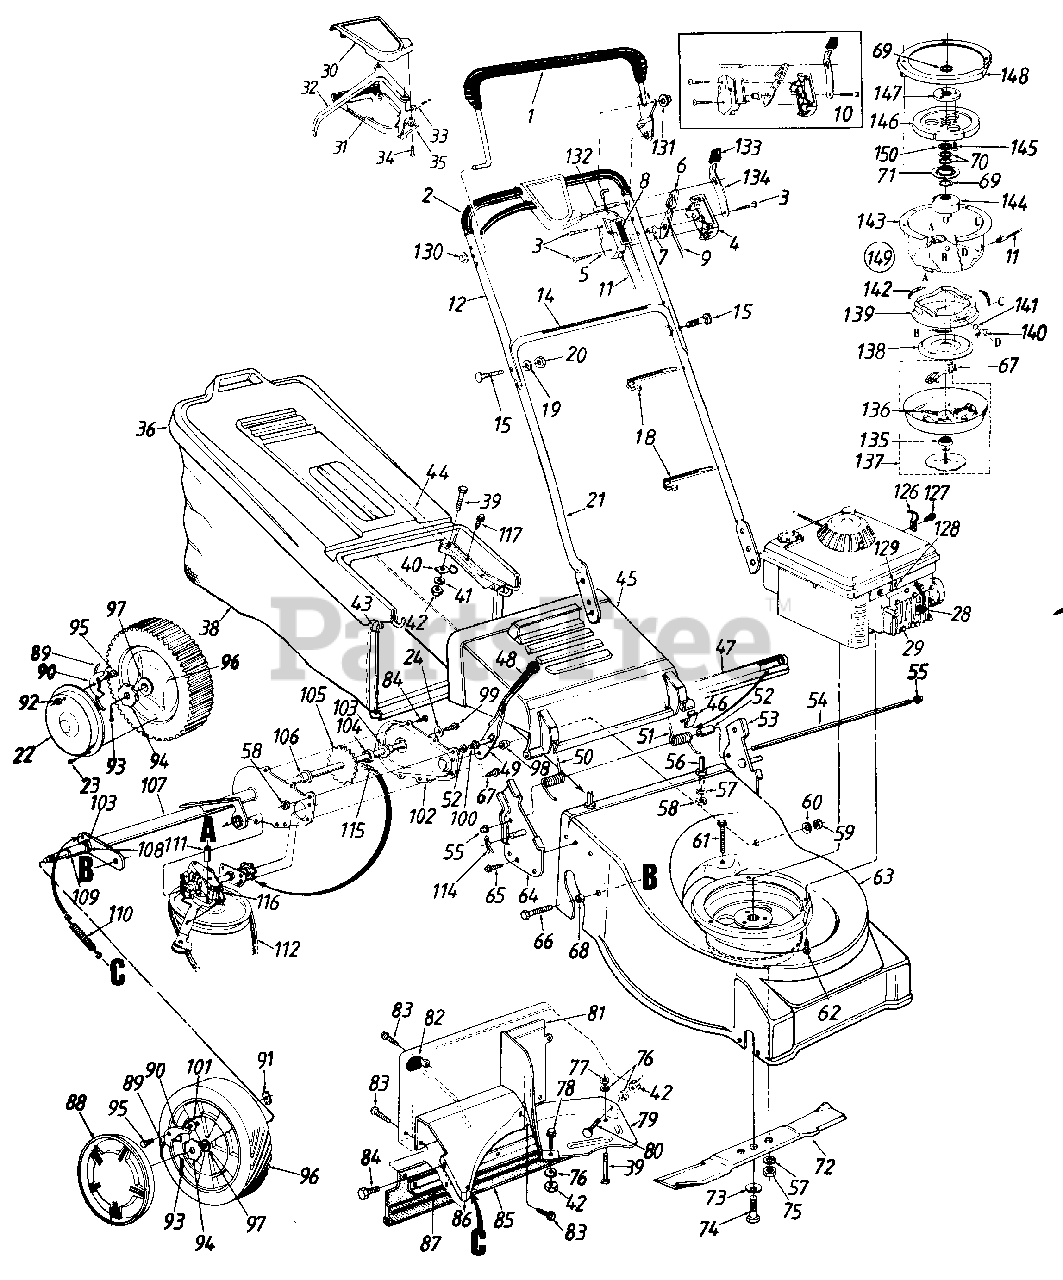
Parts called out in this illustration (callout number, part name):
1	Control Handle Ass'y.
2	Grip
3	Truss Mach. B-Tap Scr. #12 x 1.5" Lg.
4	Control Panel Half
5	Clutch Panel Half
6	Throttle Control Lever
7	Control Disc Pin
8	Control Label-Throttle
9	Throttle Wire-58" Lg.
10	Control Housing Comp.
11	Control Cable-52" Lg.
12	Upper Handle
14	Instruction Label-Handle
15	Curved Carriage Bolt 5/16-18 x 1.38" Lg.
18	Cable Tie
19	L-Wash. 5/16" I.D.'
20	Hex Nut 5/16-18 Thd.
21	Lower Handle
23	Pan Hd. Tap Scr. #12 x .50" Lg.
24	Bell-Wash. .265" I.D. x .75"
28	Spark Plug Boot
29	Engine
30	Control Cover Half-Upper
31	Control Cover Half-Lower
32	Control Lever
33	Drive Cable-53" Lg.
34	Flat C-Sunk Hd. Tap Scr. #10 x .75" Lg.
35	Cable Mtg. Cap
36	Hardtop Bag Cover
38	Grass Bag
39	Truss Mach. Scr. 1/4-20 x 1.0" Lg.
40	Mounting Clamp
41	Fl-Wash. .281" I.D. x .62"
42	Hex Nut 1/4-20 Thd.
43	Front Catcher Frame
44	Rear Catcher Frame
45	Chute Deflector
46	Deflector Plug
47	Seal-Extrusion
49	Spring Lever
50	Torsion Spring-R.H.
51	Torsion Spring-L.H.
52	Spacer.255" I.D.
53	Handle Brkt. Ass'y.-L.H.
54	Hinge Pin 17.75" Lg.
55	Cap Speed Nut
56	Shld. Pin 3/8-24 x 1.43" Lg.
57	L-Wash. 3/8" I.D.
58	Hex Jam Nut 3/8-24 Thd.
59	Hex L-Nut 3/8-24 Thd.
60	Bell-Wash. .38" I.D. x .88"
61	Hex Wash. Hd. Tap Scr. 1/4-20 x 1.5" Lg.
62	Hex L-Wash. Hd. Scr. 3/8-16 x 1.5" Lg.
63	21" Deck Ass'y.
64	Handle Brkt. Ass'y.-R.H.
65	Hex L-Wash. Hd. AB-Tap Scr. 1/4 x .62" Lg.
66	Hex Wash. Hd. Tap Scr. 3/8-16 x .75" Lg.
67	Hex Wash. Hd. Tap Scr. 1/4-20 x .5" Lg
68	Spacer.385" I.D.
69	Serrated Washer 1.0" I.D.
70	Wave Washer 1.005" I.D.
71	Serrated Pulley Half
72	21" Blade
73	Bell-Wash. .46" I.D. x .88"
74	Hex Bolt 7/16-20 x 2.0" Lg. (Gr. 5)
75	Hex Nut 3/8-24 Thd. (Gr. 8)
76	L-Wash. 1/4" I.D.
77	Hex Jam Nut 1/4-20 Thd.
78	Hex Bolt 1/4-20 x .85" Lg.
79	Rear Belt Baffle
80	Carr. Bolt lh-20 x .50" Lg.
83	Torx Mach. AB-Tap Scr. 1/4 x .62" Lg.
84	Hex B-Tap Scr. 1/4 x .38" Lg.
85	Rear Flap
89	Plastic Spring
90	Pawl.345" I.D.
91	Weld Nut 1/4-20 Thd.
92	Hex Ins. L-Nut 1/4-20 Thd.
93	Cotter Pin 1/8" Dia.
94	Ratchet Wheel 1.62" O.D.
95	Shld. Bolt .342" Dia. x .268"
96	** Wheel Ass'y. Comp.-Rear
97	** Flange Ball bearing 1/2" I.D.
98	Shld. Spacer .50" Dia.
99	Hex Bolt 1/4-20 x .62" Lg. (Gr. 5)
100	Shld. Pin 3/8-24 x 1.43" Lg.
101	Bell-Wash. .265" I.D. x .75"
102	Chain Cover Ass'y.
103	Hex Flange Brg. .506" I.D.
104	Fl-Wash. .531" I.D. x 93"
105	Rear Axle Ass'y.
106	Hex Flange Bearlng
109	Spacer.513" I.D.
110	Extension Spring 3.8" Lg.
111	Spacer.325" I.D.
112	V-Belt
114	Internal Cotter Pin 5/16" Dia.
115	#48 Chain .50" Pitch x 30 Links
116	Transmission Comp.
117	Hex AB-Tap Scr. 1/4 x .62"
126	Cable Clamp
127	Hex B-Tap Scr. #10 x .38" Lg.
128	Hex B-Tap Scr. #10 x .62" Lg.
132	Lock Pin .314" Dia. x 1.75"
133	Spring Lever Knob
134	Lockout Spring
135	Ball Brg. .669" I.D. x 1.574"
136	Comp. Spring .35" O.D. x 2.0" Lg.
137	Clutch Blade Housing Ass'y.
138	Clutch Cone
139	Brake Cup Cone
141	Steel Ball .50" Dia.
142	Ext. Spring 1.75" Lg.
143	Clutch Housing
144	Fixed Pulley Adapter
145	Flat Hd. Tap Scr. 1/4-20 x .625" Lg.
147	Flywheel Adapter
148	Engine Mounting Plate Cover
149	Blade Brake Clutch Ass'y. Comp.
150	Serrated Washer l" I.D.
